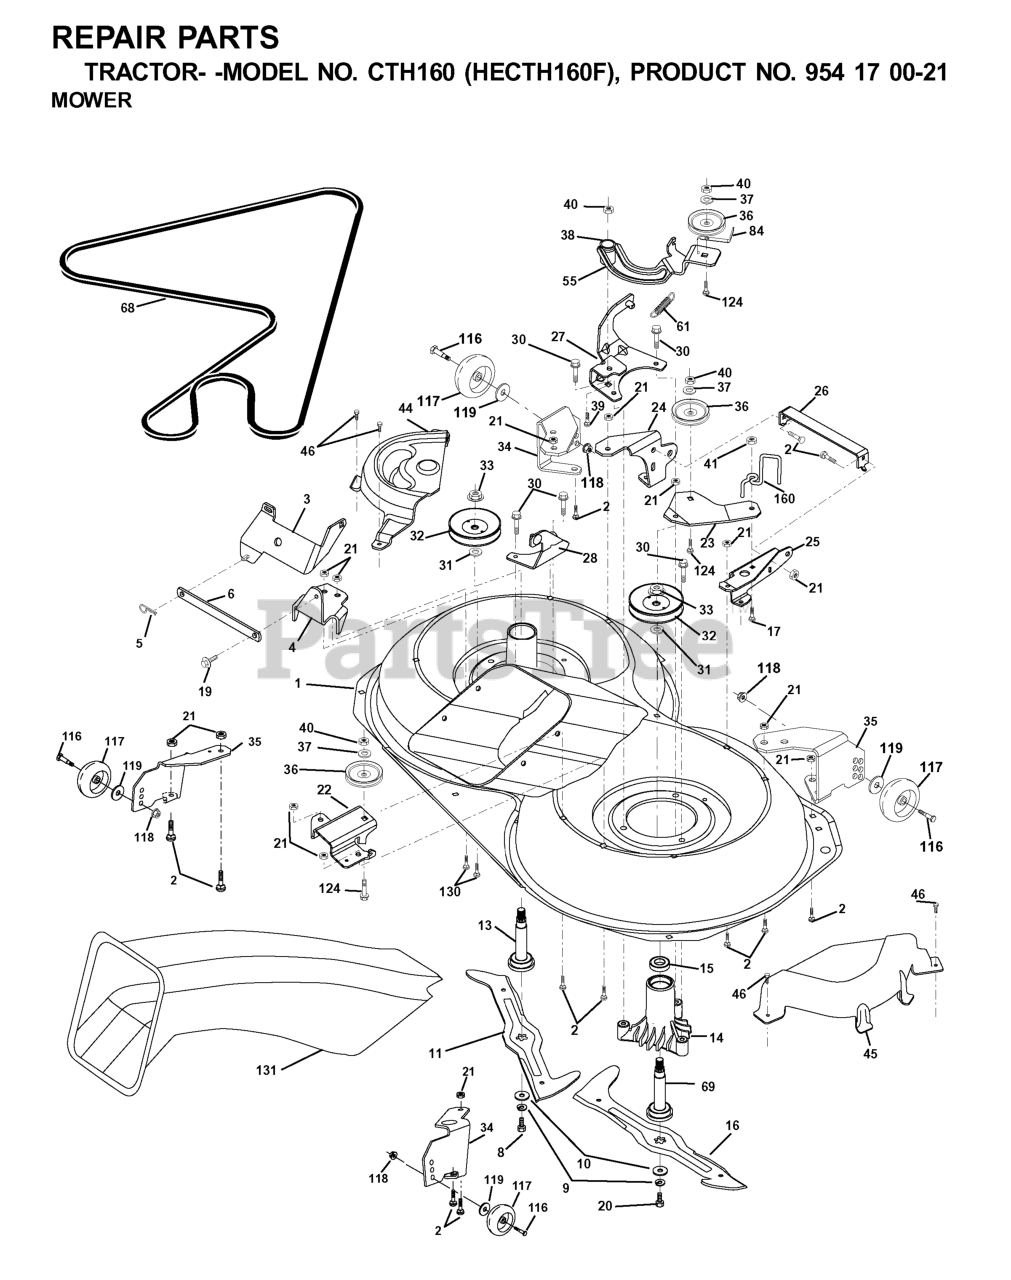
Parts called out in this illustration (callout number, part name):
1	Housing Asm. Mower 107 CRD
2	RP BOLT 5/16-18 X3/4 ZN/YEL GR
5	RETAINER-SPRNG RB
6	BAR.SWAY.92.CRD
8	BLADE BOLT
9	LOCKWASHER
10	WASHER.BLADE
11	BLADE, LH (CTH150)
13	SHAFT ASM VENT
14	HOUSING.MANDREL.VENTED (MACHD)
16	RP BLADE RH (CTH150)
17	BOLT.3/8-14X1.25
19	BOLT SHD 5/16-18
21	LOCKNUT
22	BRACKET.IDLER.RR.107.CRD
25	BRACKET.SUSPENSION.RF.107.CRD
26	BRACE.SUPT.SUSP.FRT.CRD
28	BRACKET
30	SCREW THDROL ROLLING WASHER HD
31	WASHER
33	NUT
36	PULLEY.IDLER.4.25
37	WASHER
41	NUT LOCK FLG 3/8-16 UNC
44	Cover Mandrel Lh 107 CRD
45	MANDREL COVER RH
46	SCREW.1/4-20X5/8
55	ARM.IDLER.107.CRD
68	HEX-BELT 107 MOWER
69	SHAFT.ASM.W/LWR.BRG.RH.THREAD
84	KEEPER, BELT IDLER
116	BOLT, SHOULDER
117	WHEEL GAGE DONUT
118	LOCKNUT
119	WASHER.5/16.FLAT.STE.STD.
124	BOLT.3/8-16X1.50
130	BOLT.CARR.SQNK.5/16-18UNC.X3/4
131	CHUTE BAGGER
